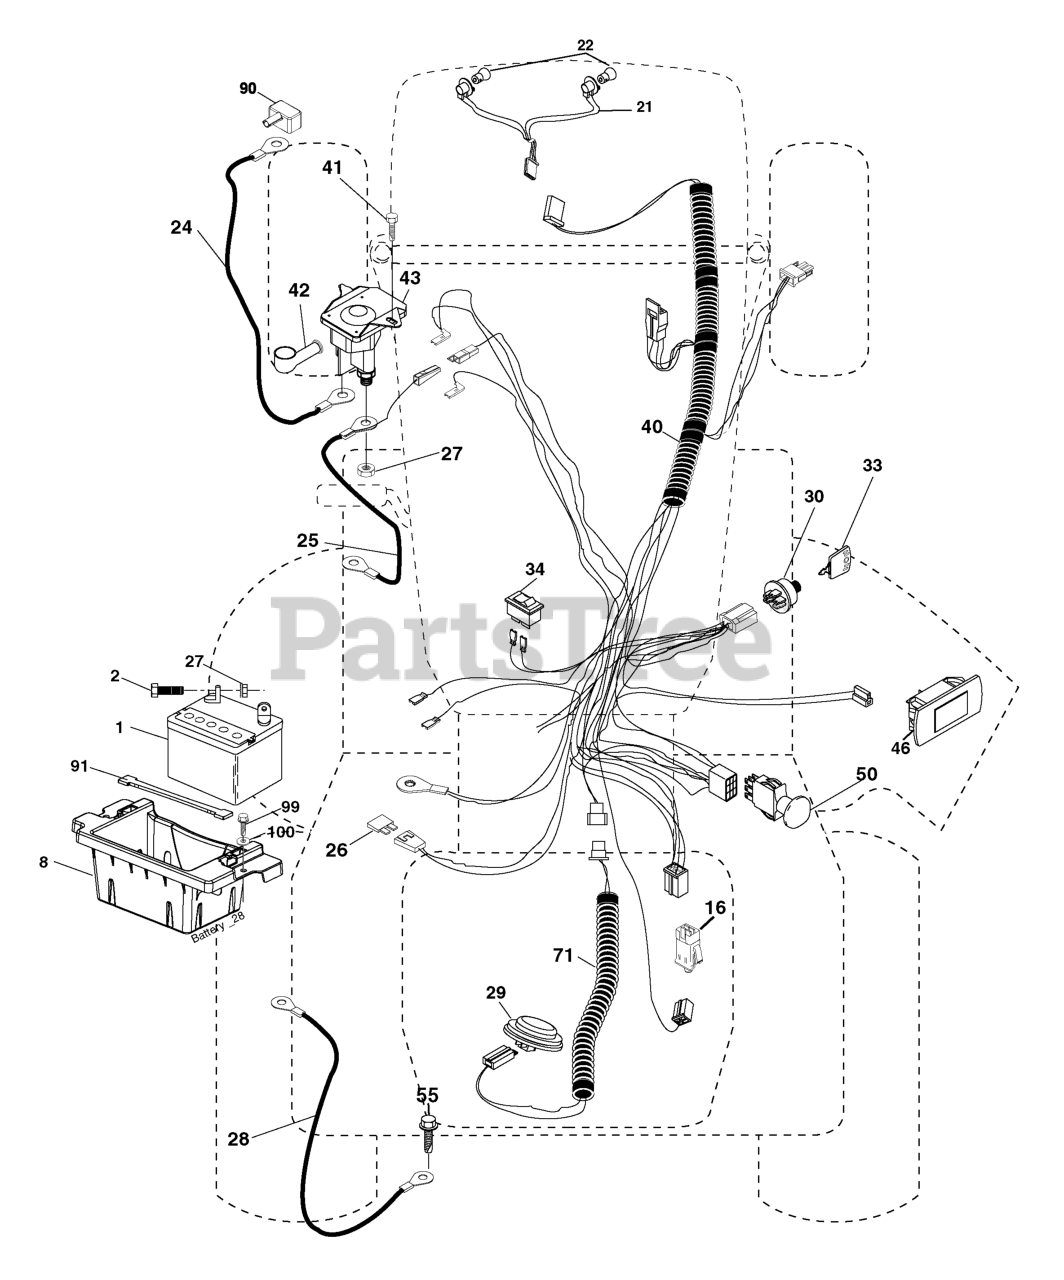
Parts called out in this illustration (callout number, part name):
1	BATTERY 12V .35 AMP
2	BOLT.HEX.1/4.X.3/4.DICHROMATE
8	BOX.BATTERY.MOUNT.FRONT.LT
16	SWITCH INTERLOOK PUSH-IN
21	HARNESS ASSY LIGHT
24	CABLE.BATT.POS.WIRE.TG.DA SOL
25	CABLE.START.RED.17.5".
26	FUSE 20AMP
27	NUT
28	CABLE GROUND 6 GA 21" 90T BLK
29	SWITCH.SEAT.DELTA.OPC.
30	SWITCH.IGN.DELTA.W.LGH.ROS
33	KEY MLD GEN DELTA
40	HARNESS.IGN.DASH.HUQ/P
41	SCREW
42	TERMINAL COVER
43	SOLENOID.W/BRASS.PLUNGER
46	GAUGE.SERVICEMINDER.HR
50	RP.PTO.SWITCH.8 TERMINAL.BLACK
55	SCREW.THDROL.5/16-18X3/4.TTY
71	HARNESS-CHASSIS SUB
90	COVER.TERMINAL.BATTERY
91	STRAP.BATTERY.MOUNT.FRONT(2 2)
99	SCREW HEXWSHR 1/4-20X3/4
100	WASHER
